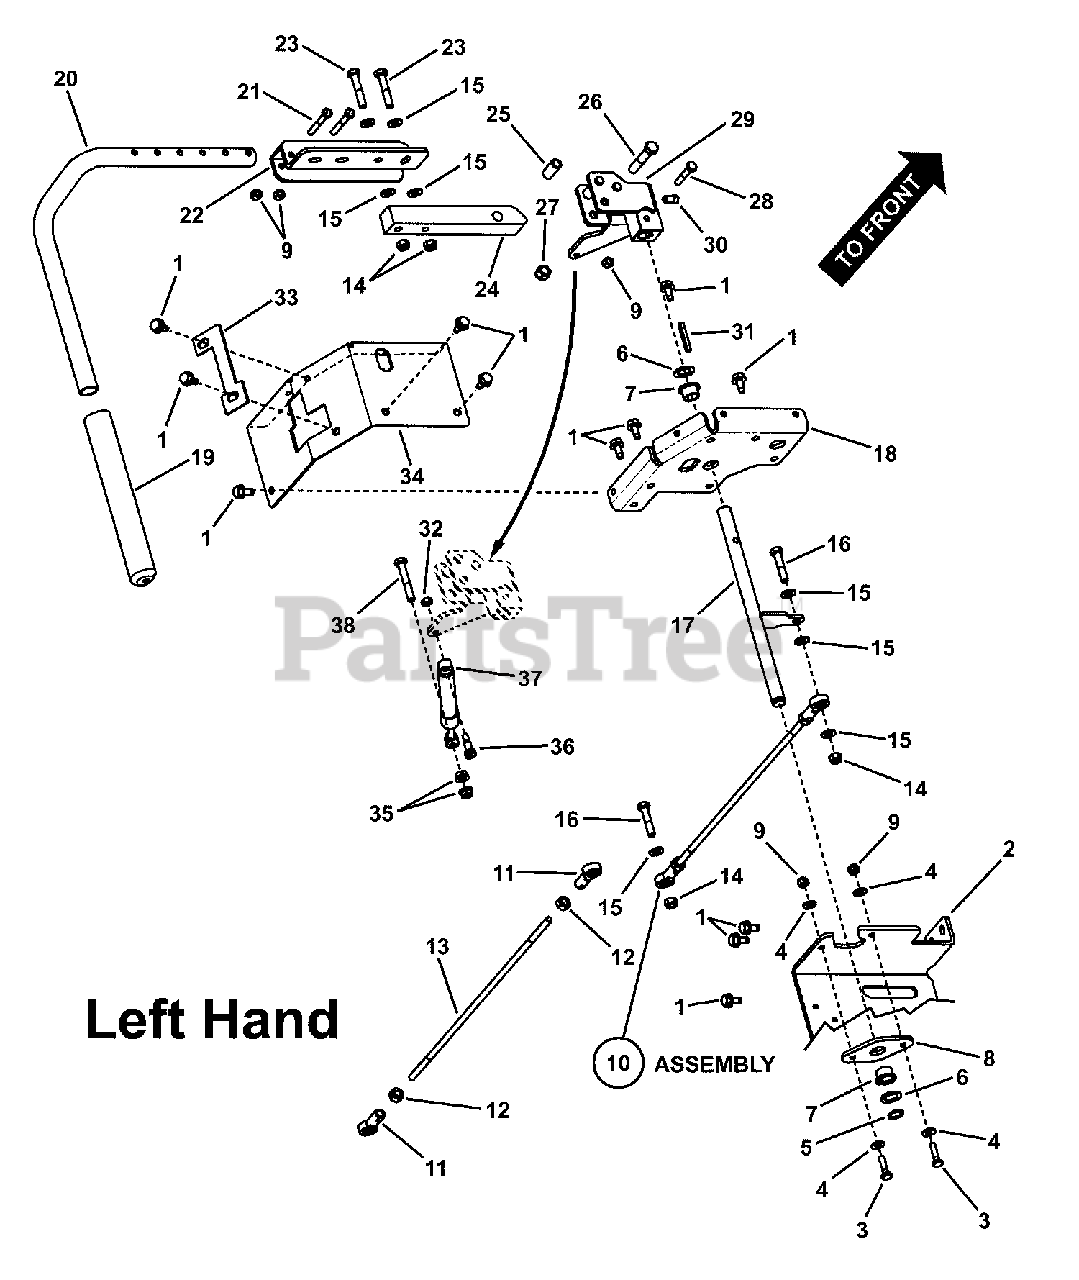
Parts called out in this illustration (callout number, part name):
1	SCREW, 5/16-18 x 5/8" Hex Washer Self-Tap
2	CHANNEL, Mounting
3	SCREW, 1/4-20 x 1" Hex Head Cap GR 5
4	WASHER, 1/4" Flat
5	RING, 5/8" External Retaining
6	WASHER, .64 I.D. x .99 O.D. x .05 Flat
7	BUSHING, Teflon Impregnated
8	MOUNTING PLATE, Left Hand Bearing
9	NUT, 1/4-20 HEX NYLON LOCK
11	ROD END (5/16-24 thread)
12	NUT, 5/16-24 Hex, GR 5 or B
13	LINKAGE ROD, Pump Control (5/16-24 thread)
14	NUT, 5/16-18 HEX NYLON LOCK
15	WASHER, 5/16" Flat
16	SCREW, 5/16-18 x 1-1/2" Hex Head Cap, GR 5
17	WELDMENT, Cross Rod
18	BUSHING MOUNT PLATE, Left Hand
19	GRIP, Twin Stick
20	HANDLEBAR, Twin Stick
21	SCREW, 1/4-20 x 1-3/4" Hex Head Cap, GR 5
22	BRACKET, Handle Adjustment
23	BOLT, 5/16-18 X 1-3/4 GD5 YZ
24	MOUNTING ARM
25	SPACER, .498 O.D. x 1.010" long
26	SCREW 3/8-16 x 2" Hex Head Cap, GR 5
27	NUT, 3/8-16 HEX NYLON LOCK
28	SCREW, 1/4-20 x 1-1/2" Hex Head Cap GR 5
29	WELDMENT, Mounting Hub, LH
30	SET SCREW, 5/16-18 x 1/2" Square Head Cup Point
31	KEY, 3/16" Square x 1-1/2"
32	NUT, 1/4-20 Hex Center Lock
33	PLATE, Speed Adjuster
34	PLATE, Bushing Mount, LH
35	NUT, 5/16-18 Hex Flange Lock
36	SCREW, 1/4-20 Shoulder Socket Head
37	DAMPENER, Hydraulic
38	BOLT, 5/16-18 X 2", GD5
